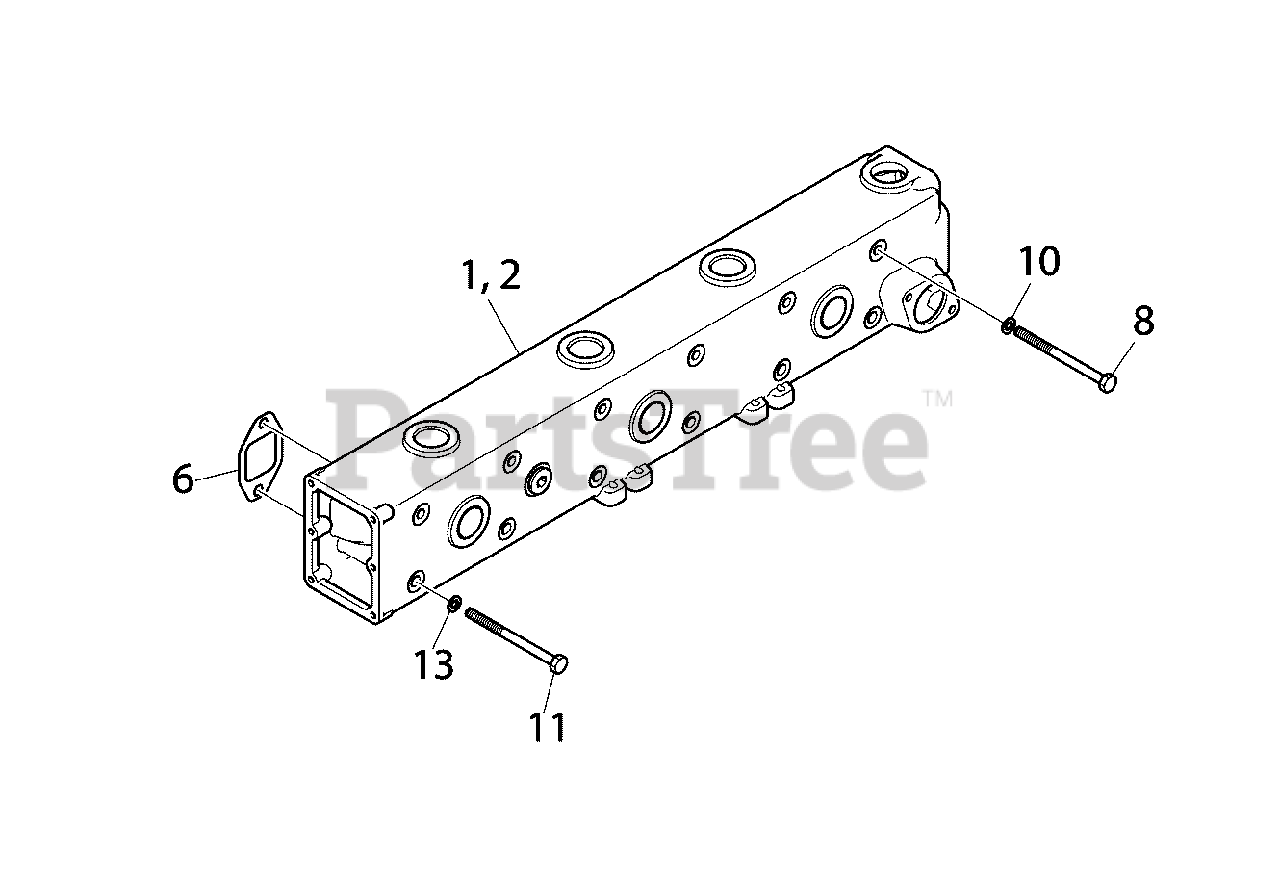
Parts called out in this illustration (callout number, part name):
1	* MANIFOLD, EXHAUST
2	* MANIFOLD
6	GASKET, E/MANIFOLD
8	* BOLT, HEX
10	* WASHER, SPRING
11	* BOLT, HEX
13	* WASHER, SPRING
